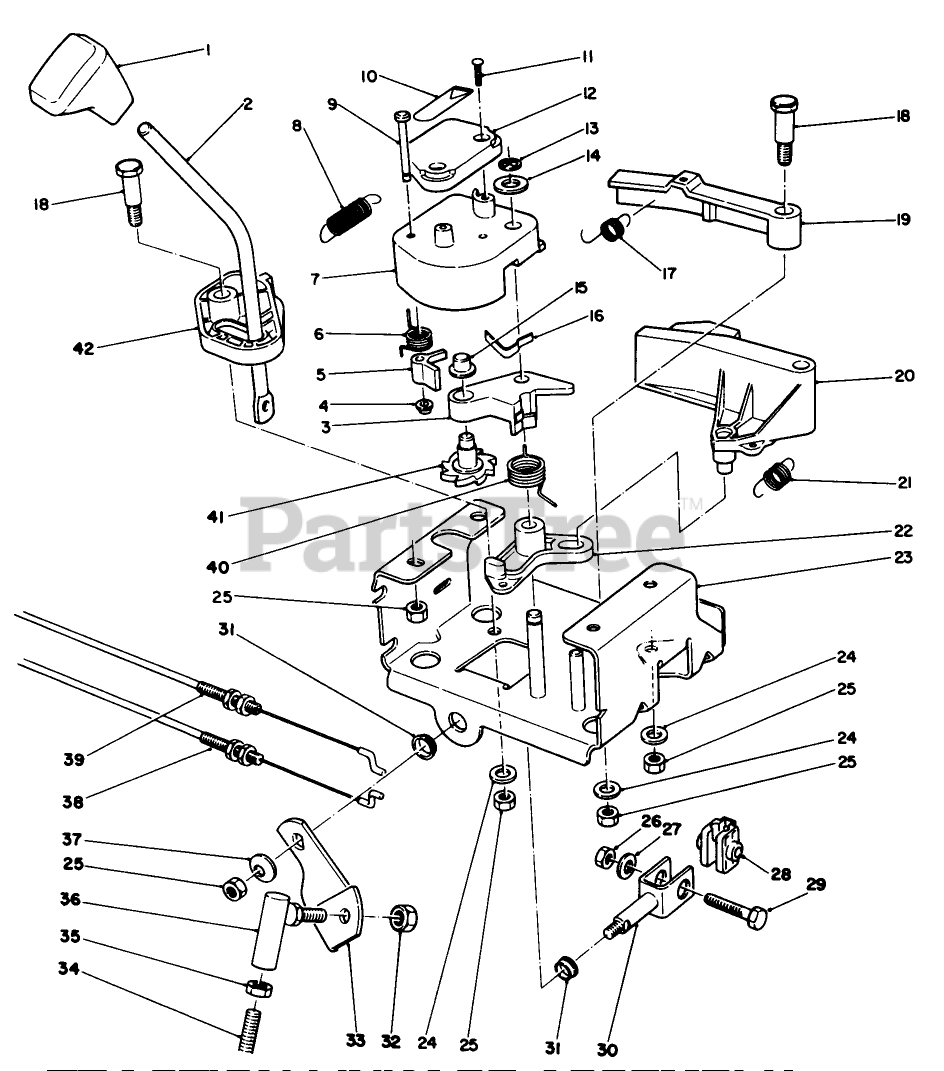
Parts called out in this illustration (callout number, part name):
1	KNOB-SHIFT
2	ROD-SHIFT
3	LEVER-WHEEL, INDEX
4	NUT-PUSH
5	TANG-INDEX
6	SPRING-TORSION
7	LEVER LATCH
8	SPRING-EXTENSION
9	PIN-TANG
10	DECAL
11	SCREW-PPH
12	COVER-LATCH
13	RING-RETAINING
14	WASHER-THRUST
15	NUT-PUSH
17	SPRING-EXTENSION
18	SCREW-SHOULDER
19	LEVER-LOCKOUT
20	LEVER-REVERSE
21	SPRING-EXTENSION
22	LEVER-REVERSE, SWITCH
24	WASHER-PLAIN
25	NUT-LOCK, NI
26	NUT-LOCK, NI
27	WASHER-FLAT
28	RETAINER-ROD, SHIFT
29	CAPSCREW
31	BUSHING
33	BRACKET-SHIFT
34	ROD-BENT SHIFT, LOWER
35	NUT-HJ
37	WASHER-BELLEVILLE
38	CABLE-GEARBOX
39	CABLE-ARM, LATCH
40	SPRING-TORSION
41	WHEEL-INDEX
42	BASE-LOCKOUT
